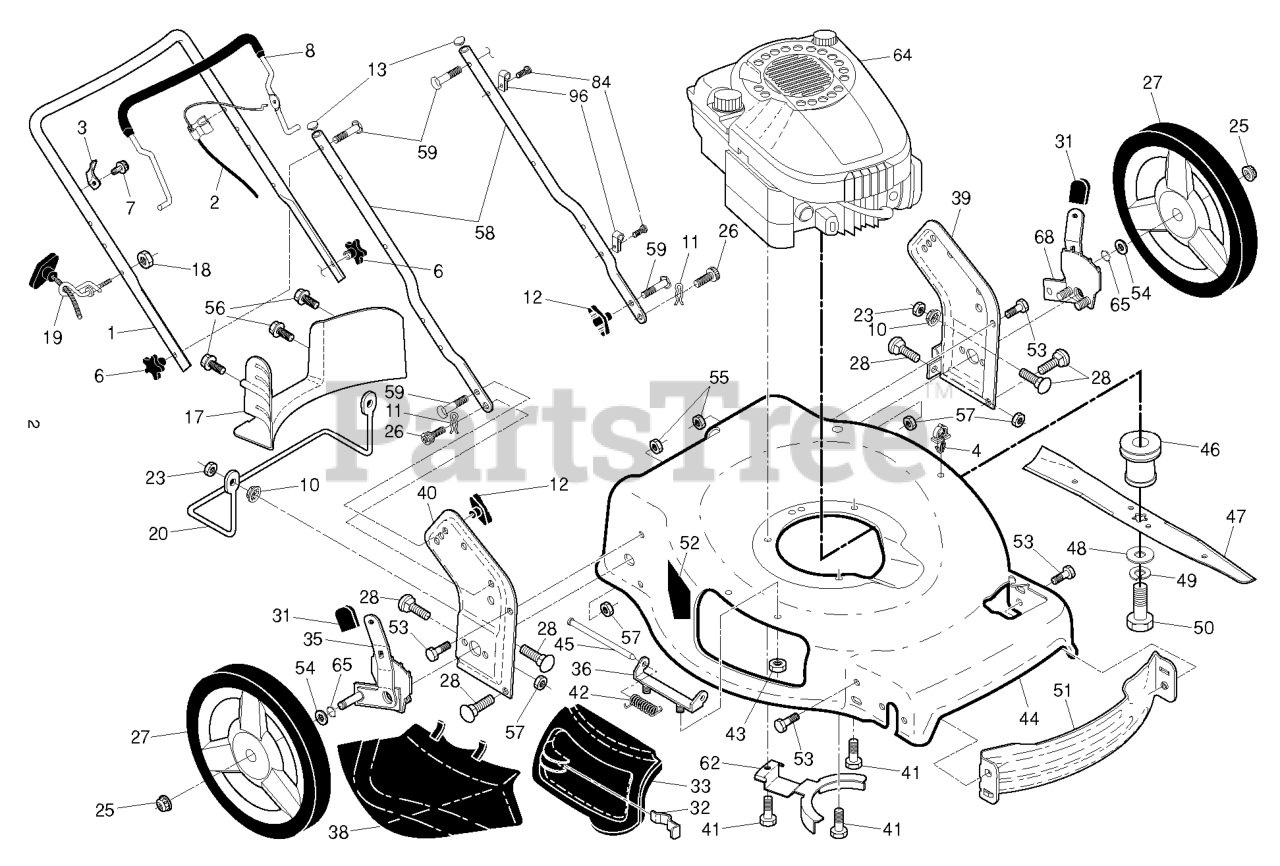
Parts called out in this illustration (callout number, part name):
1	HANDLE.UP.CURV.PUSH/SSDRV.GREY
2	CABLE.MZR.FGD.22+.ERGO
3	BRACKET.UPSTOP.RT
6	KNOB.HANDLE.PLASTIC.STAR.BLACK
8	BAIL.OVER.MOLD.ERGO.MZR.ORANGE
10	WASHER 5/16"
11	COTTER.HAIRPIN.DOOR/HANDLE.PIV
12	KNOB, DEFLECTOR
13	PLUG.PLASTIC.7/8".14-20.GAUGE
17	BAFFLE.22PLUS.FGD.REAR.
18	NUT
19	RB GUIDE.ROPE.STD.BLK.ZIN WSL
20	FOOTGUARD.REAR.22PLUS.BLK
23	LOCKNUT-FLANGE 5/16-18
25	NUT.HEX.FLANGE.3/8-16.LOCKNUT
26	SCREW,DOOR/HANDLE.PIVOT
27	WHEEL.12 X 1.75 CFH3SPK.RAD3
28	BOLT
31	SELECTOR KNOB
32	LATCH.DOOR.ZINC
33	DOOR.MULCH.22 PLUS.HUSQ.GREY
35	ADJUSTER.ASM.9POS.HW.R/R
36	BRACKET.ASM.HINGE.21.FWGD.
38	DEFLECTOR.CLIPPING.22.BLACK
39	BRACKET.ASM.HNDL.LT.22+.GREY
40	BRACKET.ASM.HNDL.RT.22+.GREY
41	BOLT 3/8-16X1-1/8
42	SPRING.TORSION
43	NUT.HEX.FLANGE.1/4
44	KIT.HSG.22+FGD.SIDE.668.CE
45	ROD.HINGE.21
46	ADAPTOR BLADE 25MM STAR
47	BLADE 22 4-N-1 2PIN 5STAR BLK
48	WASHER,HARDEN
49	LOCKWASHER
50	SCREW, HEX HD 3/8-24 X 1-3/8
51	BAFFLE.FRONT.22.PLUS
52	DECAL.INTERNATIONL.CUTFINGER
53	BOLT.5/16HEX.WHS.HD
54	WASHER.FLAT.1/2
55	NUT.HEX.FLANGE.1/4
56	SCREW.HX.13X.750
57	NUT.FLANGE.5/16
58	HANDLE.LOWER.22+BT.2PC.GRY
59	BOLT, HANDLE 5/16-18X1.75
62	BRACKET.ENG/BELTKEEPER
65	O-RING..070X.487.NEOPRENE
68	ADJUSTER.ASM.9POS.HW.R/L
84	FASTENER.PUSH.O.250X0.783
96	CLIP.CABLE.BLK
